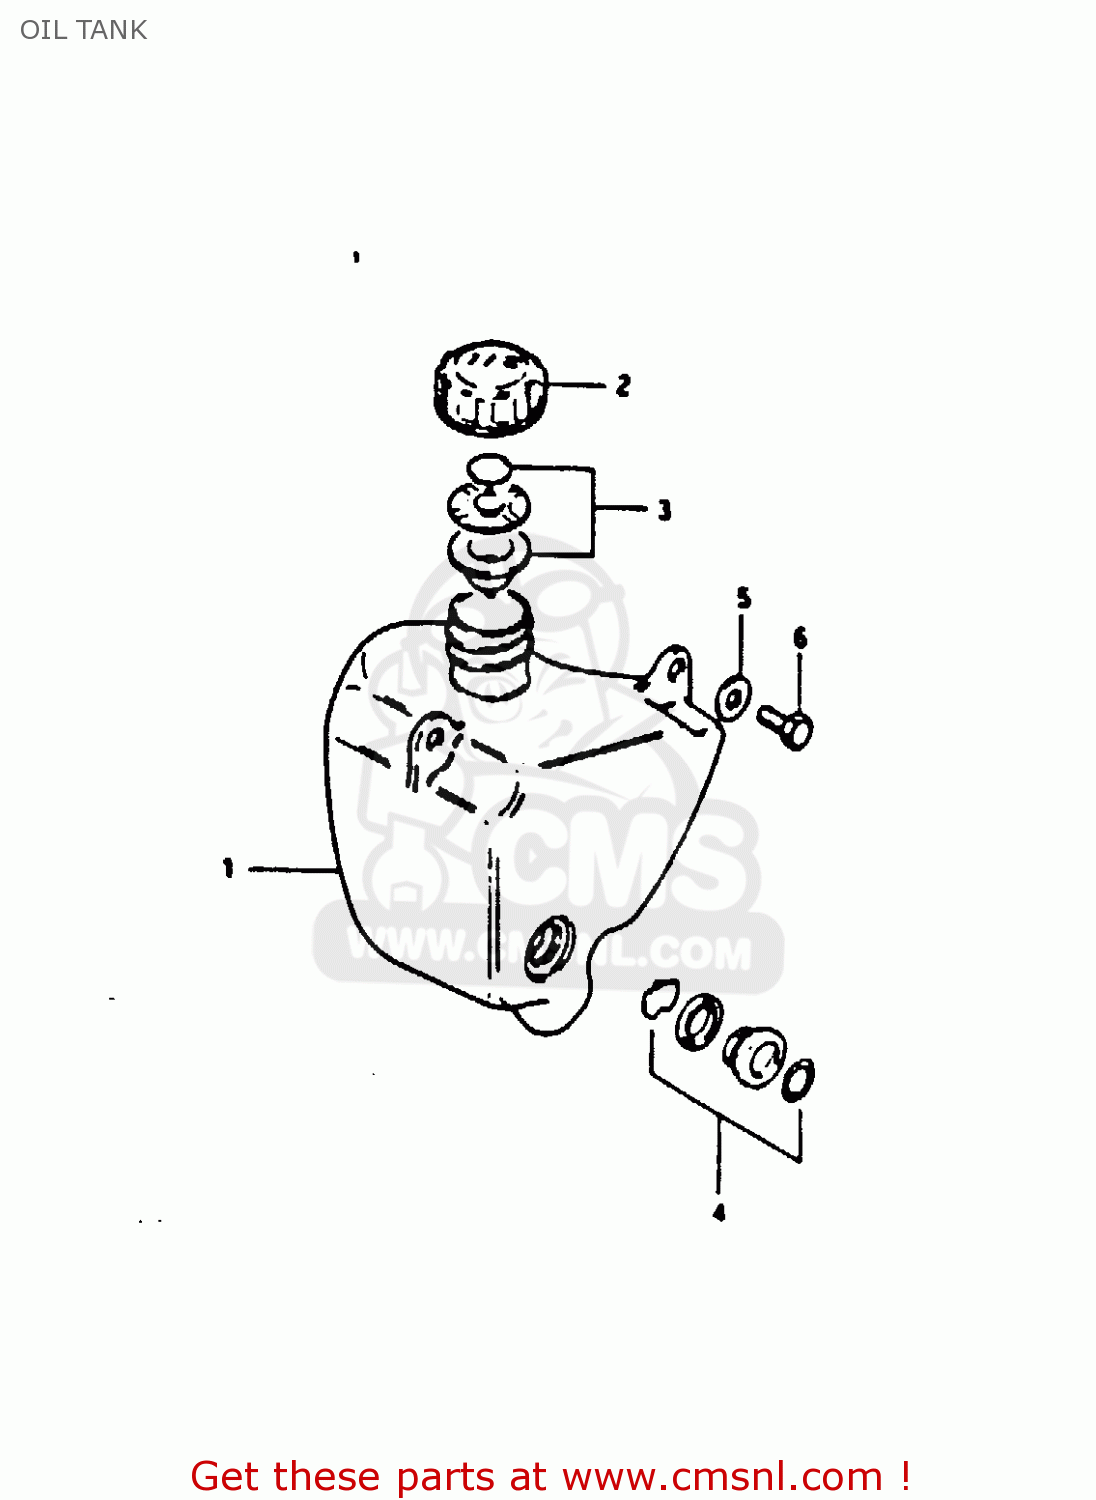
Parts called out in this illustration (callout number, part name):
1	TANK,OIL
2	CAP,OIL TANK
3	GASKET SET (NAS)
4	LENS SET,OIL LEVEL
5	WASHER
6	BOLT, UPPER
